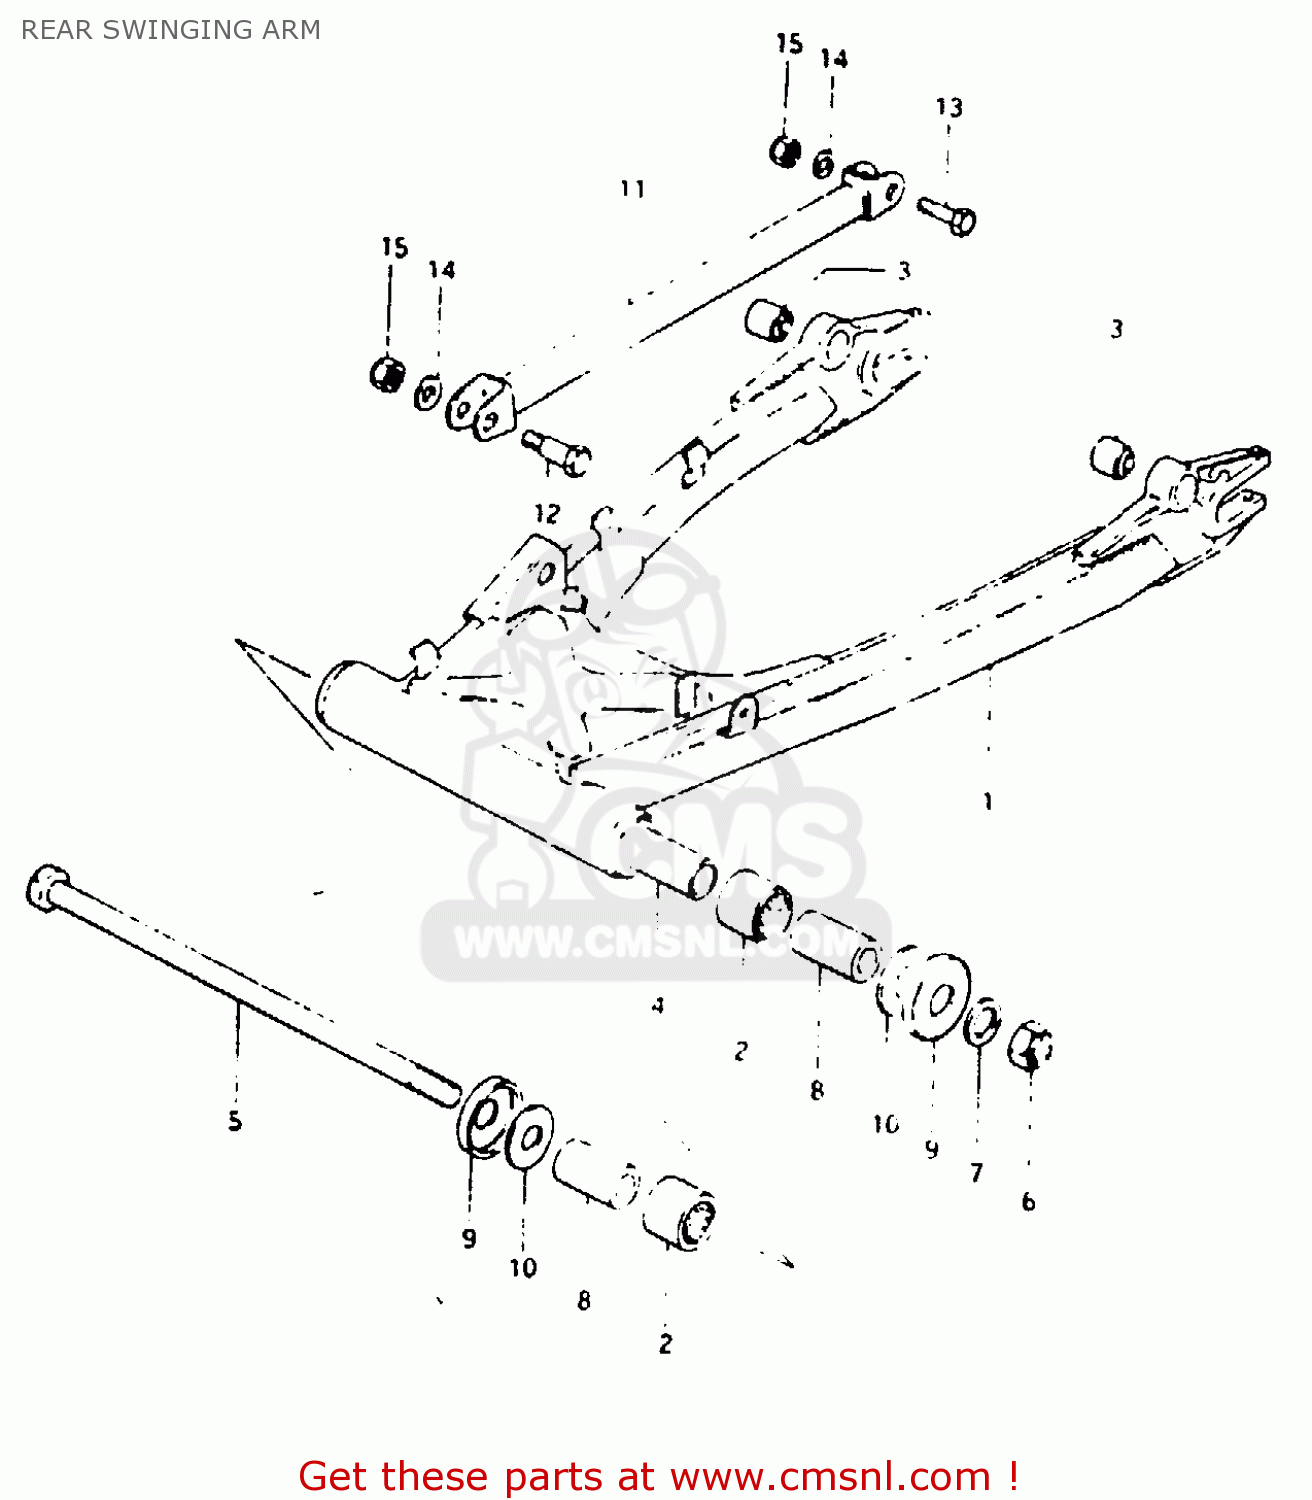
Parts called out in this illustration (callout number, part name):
1	SWING ARM ASSEMBLY,REAR
2	BEARING(25X33X30)
3	BUSH
4	SPACER,RR SWGARM PIVOT CTR
5	SHAFT,REAR SWING ARM
6	NUT 16MM
7	WASHER
8	SPACER,RR SWGARM PIVOT
9	COVER,RR SWINGINGARM PIVOT
10	WASHER
11	TORQUE LINK, REAR
12	BOLT
13	BOLT(10X39)
14	WASHER
15	NUT
